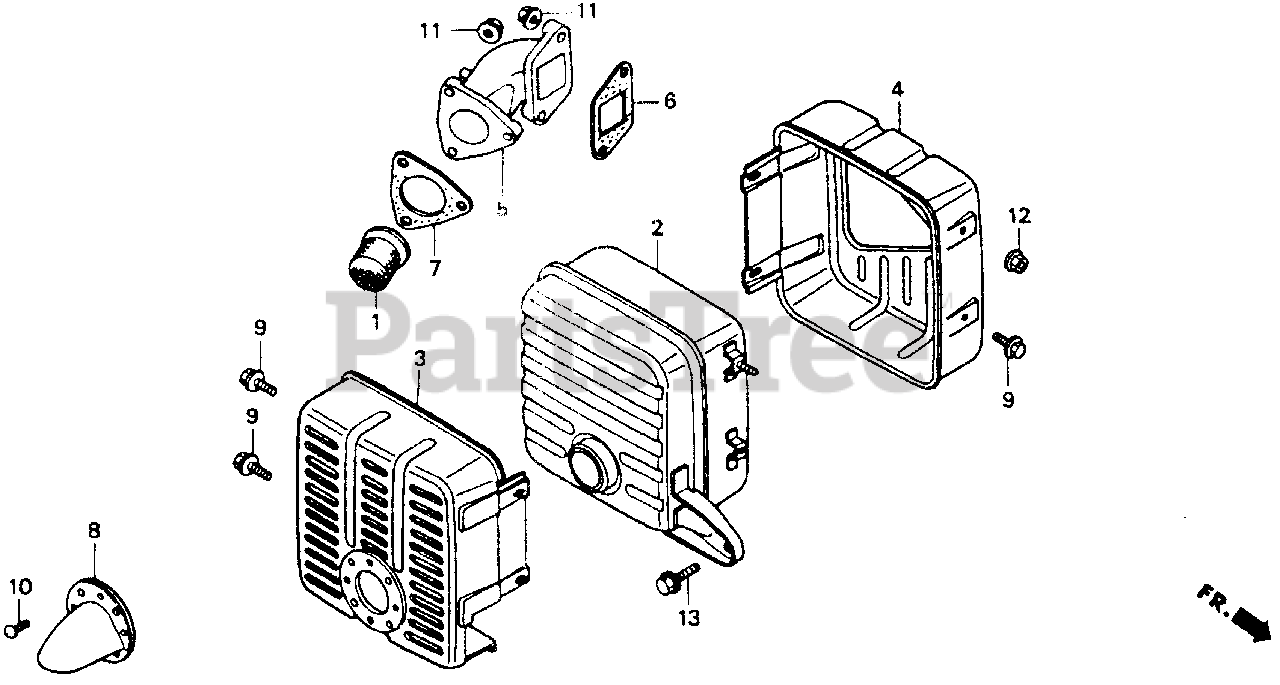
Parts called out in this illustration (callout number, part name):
1	ARRESTER, SPARK
2	MUFFLER
3	PROTECTOR A, MUFFLER
4	PROTECTOR B, MUFFLER
5	PIPE, EX.
6	GASKET, EX. PIPE (NON-ASBESTOS)
7	GASKET, MUFFLER (NON-ASBESTOS)
8	DEFLECTOR, MUFFLER
9	BOLT, FLANGE (5X8)
10	SCREW, PAN (5X8)
11	NUT, FLANGE (8MM)
12	NUT, FLANGE (8MM)
13	BOLT, FLANGE (8X20)
